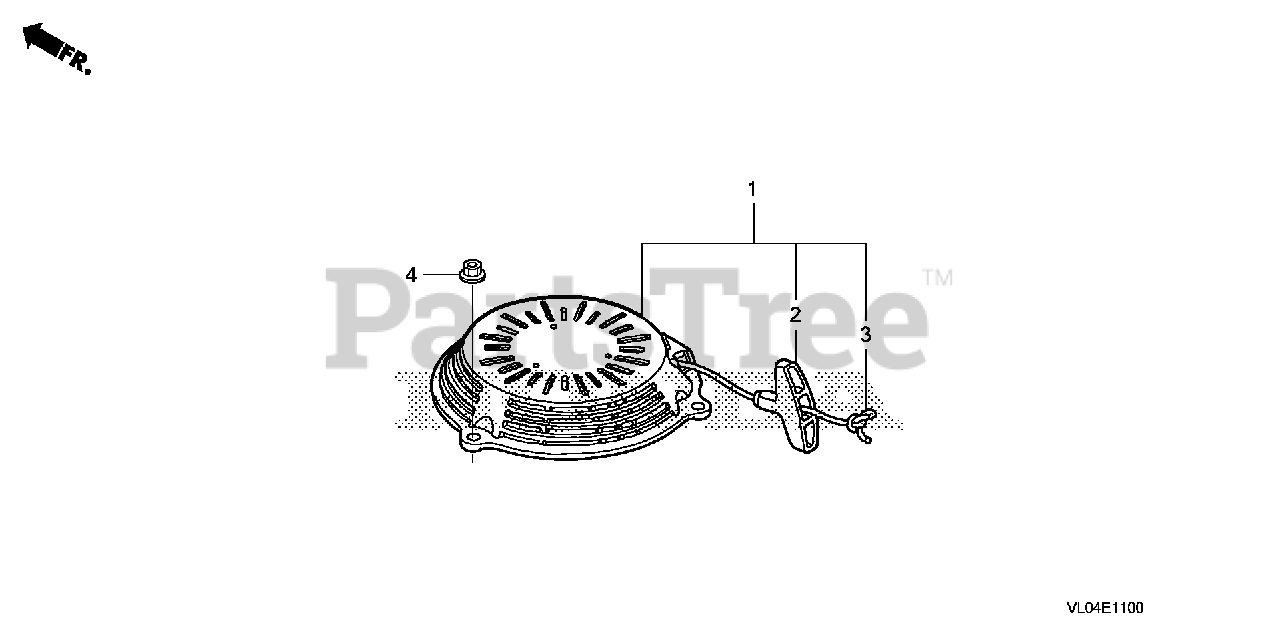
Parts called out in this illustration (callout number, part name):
1	STARTER ASSY., RECOIL *R280* (LONG ROPE) (POWER RED)
2	GRIP, STARTER
3	ROPE, RECOIL STARTER (LONG TYPE)
4	NUT, FLANGE (6MM)
